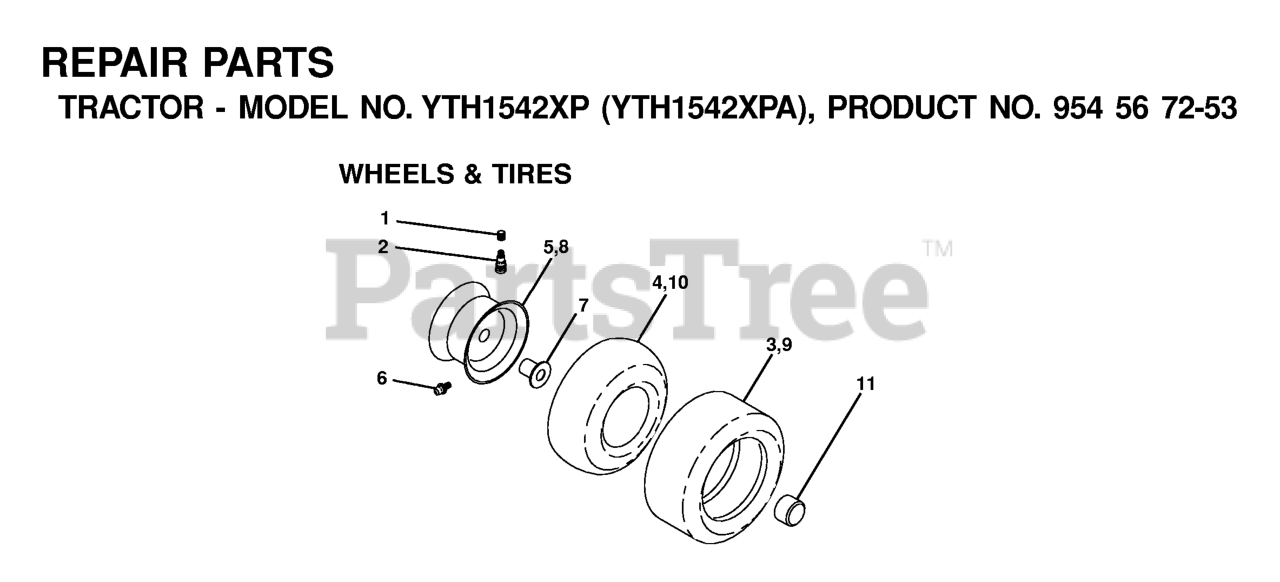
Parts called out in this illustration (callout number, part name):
2	VALVE STEM LT
3	TIRE HEAVY DUTY
4	TUBE.5.3/4.5/6
5	RIM ASM 6" FRONT SILVER
6	FITTING LT
7	BEARING T
8	RIM ASM 8" REAR SILVER
9	TIRE.TS.20X10-8
10	TUBE
11	CAP, AXLE BLK
